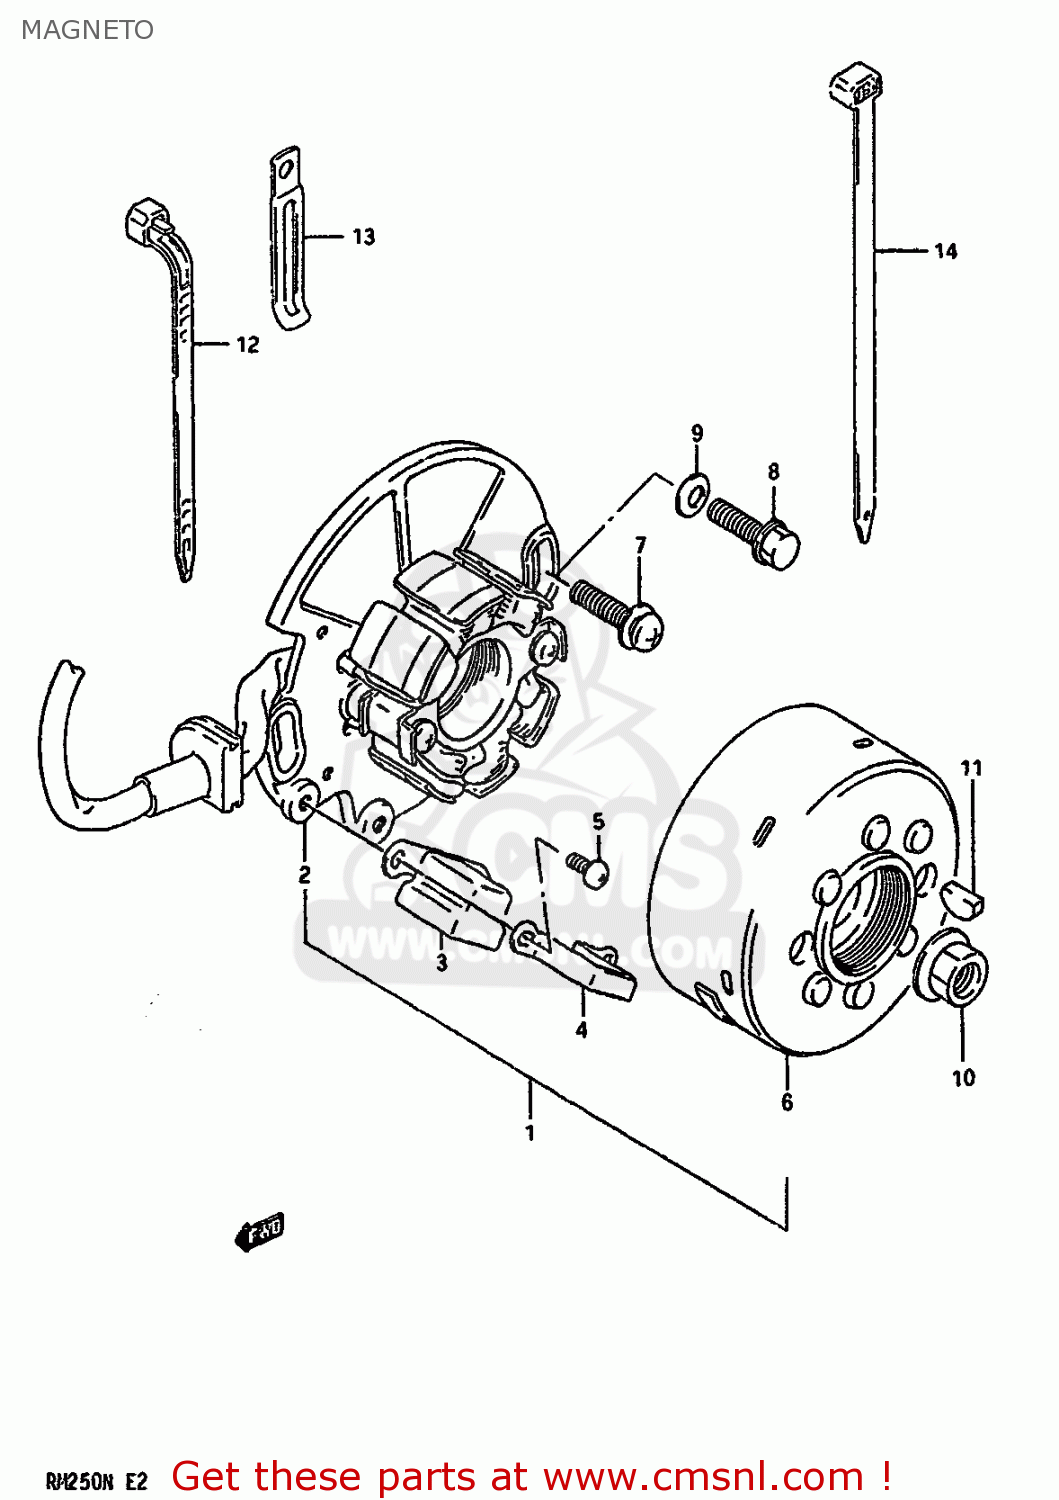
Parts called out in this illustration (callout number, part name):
1	MAGNETO ASSEMBLY
2	STATOR ASSEMBLY
3	COIL ASSEMBLY,PICK-UP
4	HOLDER,PICK UP COIL
5	SCREW
6	ROTOR
7	SCREW
8	BOLT
9	WASHER
10	NUT
11	KEY 4MM
12	CLAMP(L:235)
13	CLAMP
14	CLAMP
